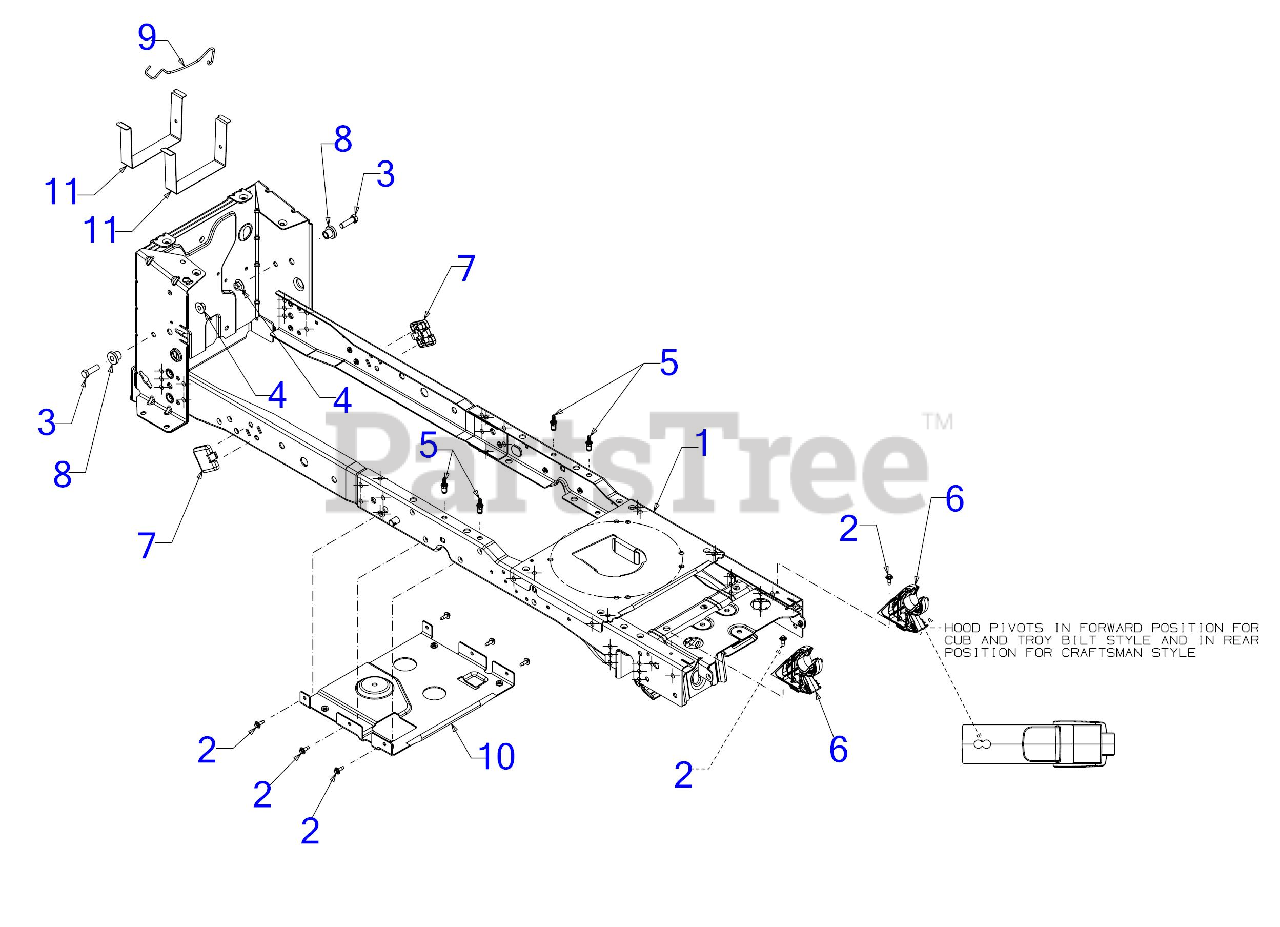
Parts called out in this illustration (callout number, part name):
1	DIFF LOCK FRAME ASSEMBLY
2	SCREW M6-1 x .625
3	SCREW 3/8-16 x 1.25 GR5
4	FLANGE LOCK NUT
5	RIVET-HEX STUD 1/4-20 FRM
6	HOOD PIVOT BRACKET
7	LIFT ROD WEAR PAD
8	SHOULDER SPACER
9	BATTERY HOLD DOWN ROD
